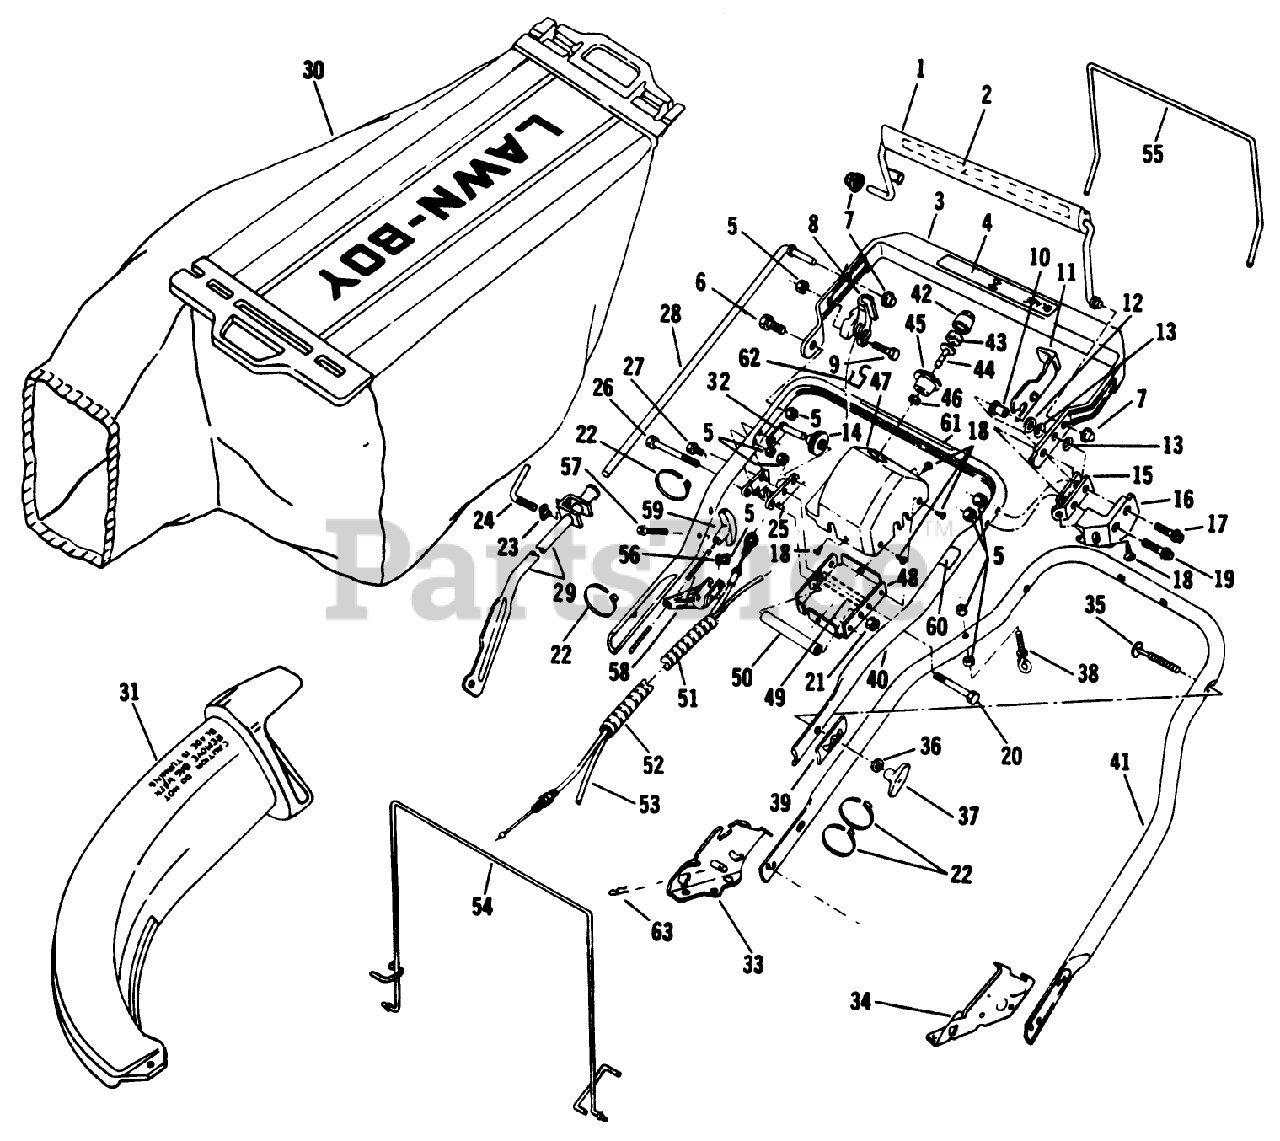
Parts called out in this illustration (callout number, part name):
5	LOCKNUT E
6	BOLT
10	SPACER
12	WASHER M
15	DOWN STOP
16	LOCKOUT GUARD
17	BOLT SHOU
18	SCREW F
19	SCREW
26	BOLT-CONSOLE
28	CONTROL ROD
35	BOLT QUALITY
36	WASHER-CURVED
37	NUT-WING
38	EYE BOLT WAS MFG
39	BRACKET R/B 613462
43	FILTER S
46	LOCKNUT S
49	SPACER
54	Hanger Assembly Front
55	HANGER
56	WASHER
59	HANDLE,STARTER
63	HAIR PIN
